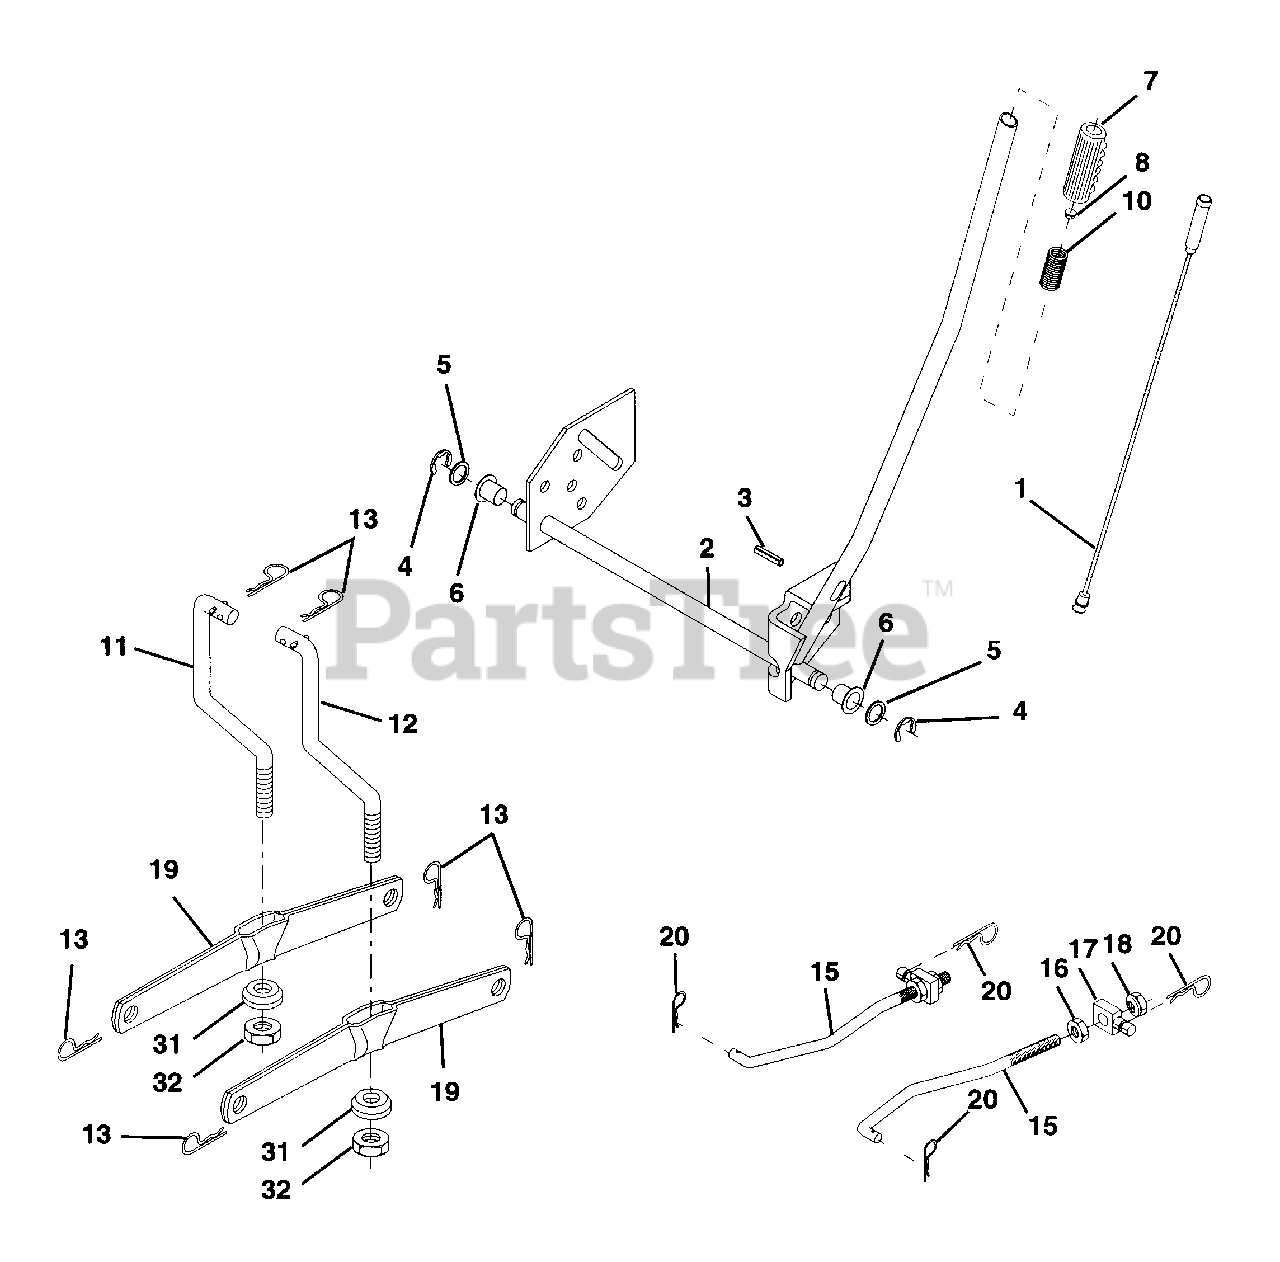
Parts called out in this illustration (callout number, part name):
1	Wire Asm Inner W/plunger 17 32
2	Shaft Asm Lift
3	Pin Groove
4	E Ring #5133-62
5	Washer PLTD 21/32 X 1 X 21ga
6	Bearing Nylon Blk 629 Id
7	Grip Handle Bicycle
8	Button Plunger Black
10	Spring Cprsn 3 750 Oiled
11	Link Lift LH
12	Link Lift RH
13	Retainer Spring
15	Link Front
16	Nut Jam Hex 1/2-13 Unc
17	Trunnion Blk Zinc
18	Nut Lock W/wsh 1/2-13unc
19	Arm Suspension Rear
20	Spring, Retainer
31	Bearing Pvt. Lift Spherical
32	Nut Crownlock 3/8-24
